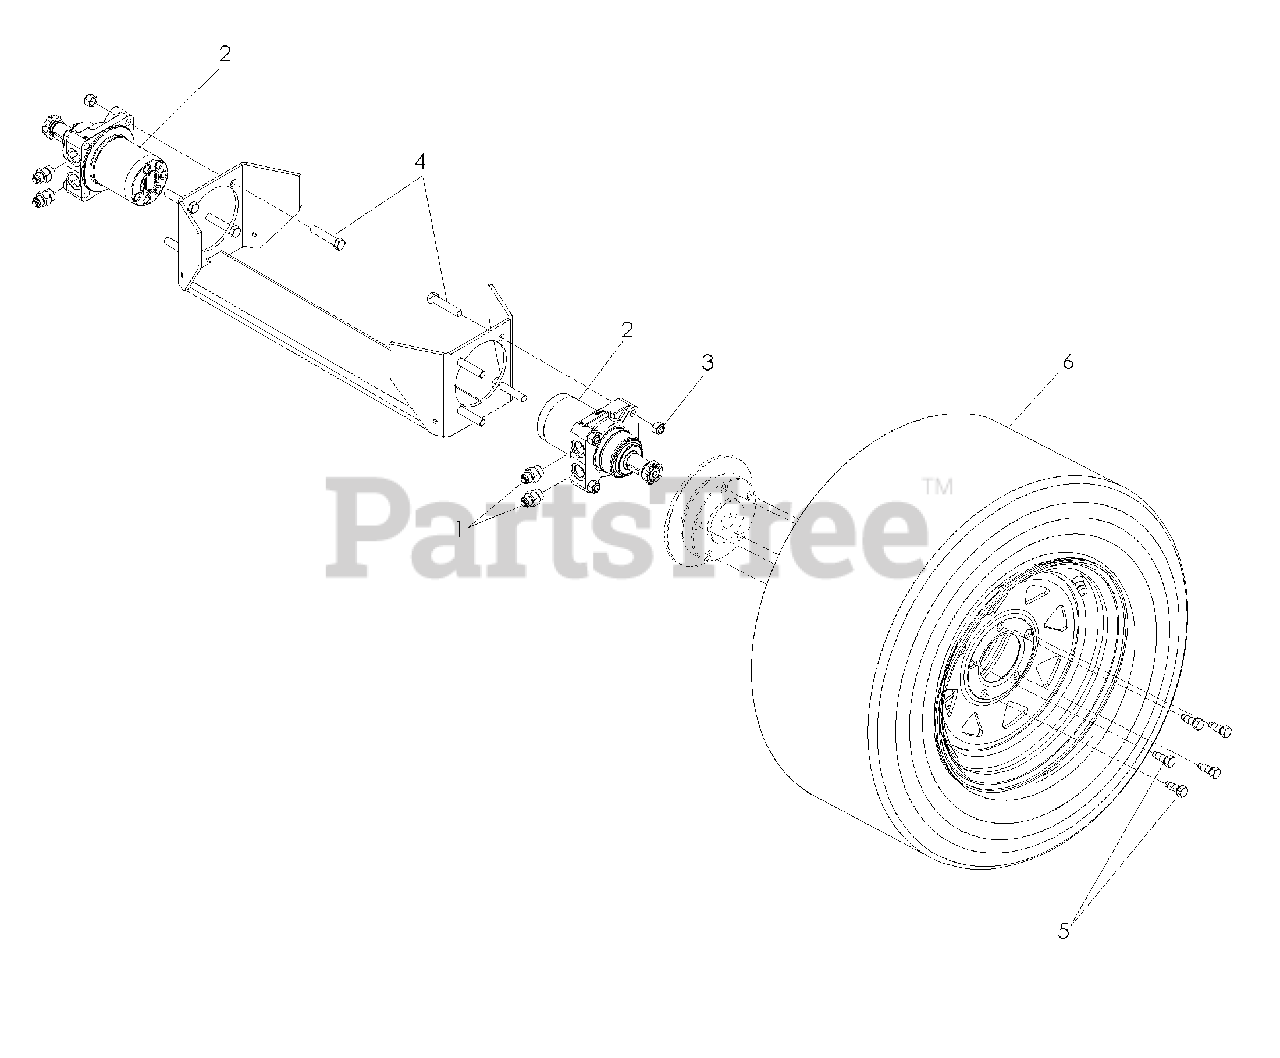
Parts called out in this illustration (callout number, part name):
1	STRAIGHT CONNECTOR
2	WHEEL MOTOR, TJ
3	NUT 1/2 HEX NYLOC
4	HCS 1/2-13 x 2 1/2
6	TIRE, 23 x 10.50
